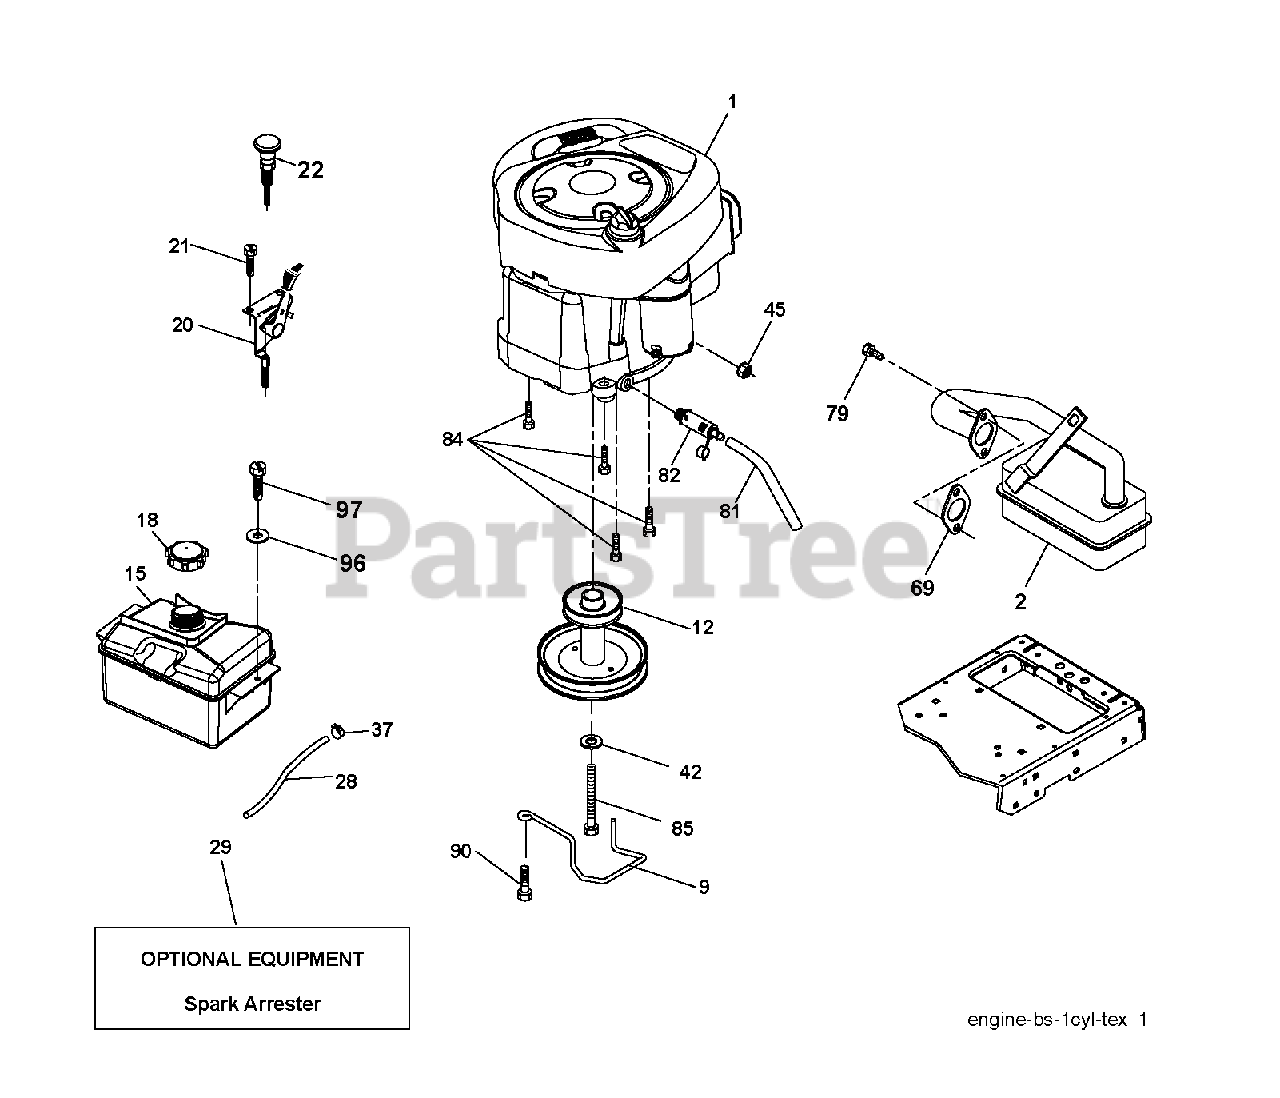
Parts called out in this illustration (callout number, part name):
9	KEEPER.BELT.ENGINE.3.25
12	PULLEY ENGINE
15	TANK FUEL FRT 1.5 GAL
18	FUEL CAP
20	CONTROL.TH/CK.C.
21	SCREW
28	LINE.FUEL.20
29	ARRESTER SPARK (OPTIONAL)
37	HOSE CLAMP
42	LOCKWASHER
45	NUT
69	REPL BY 532 27 22-93
79	SCREW.SOCKET HD.5/16-1
81	TUBE, DRAIN OIL ASM.
82	PLUG DRAIN OIL EASY
84	SCREW.3/8-16
85	BOLT HEX 7/16-20X4-1/4"
90	SCREW 3/8-16X1
97	SCREW HEXWSHR 1/4-20X3/4
